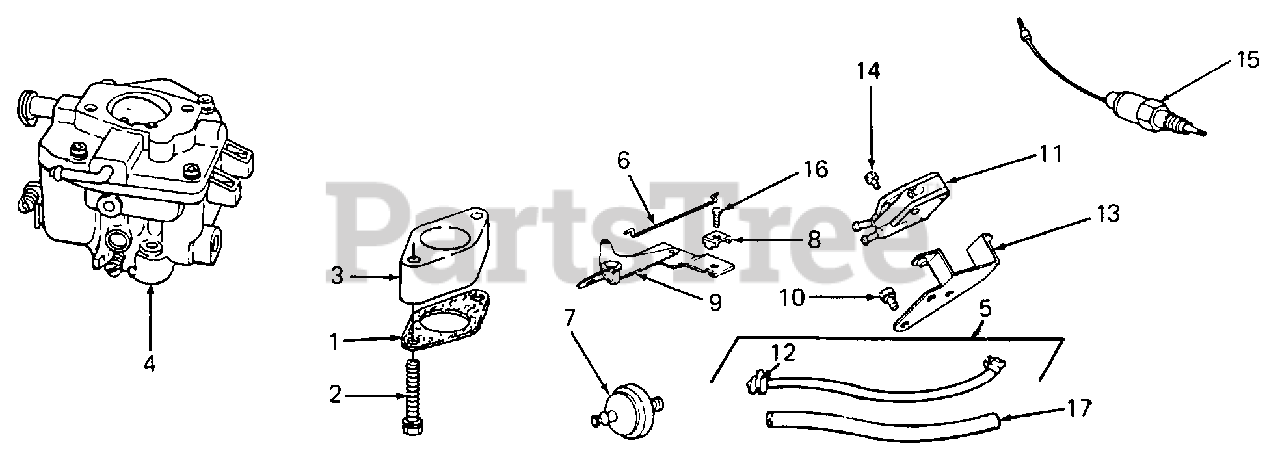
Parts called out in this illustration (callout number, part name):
1	Gasket, Carburetor Mtg
2	Screw, Sems
3	Spacer, Carburetor
4	Carburetor Assy
5	Line, Fuel
6	Link, Choke
7	Filter, Fuel
8	Clamp, Casing
9	Bracket, Choke
10	Screw, Sems
11	Pump, Fuel
12	Clamp, Fuel Line
13	Bracket, Fuel Pump
14	Screw, Mtg
15	Solenoid
16	Screw, Hex Hd
17	Insulation, Fuel Line
